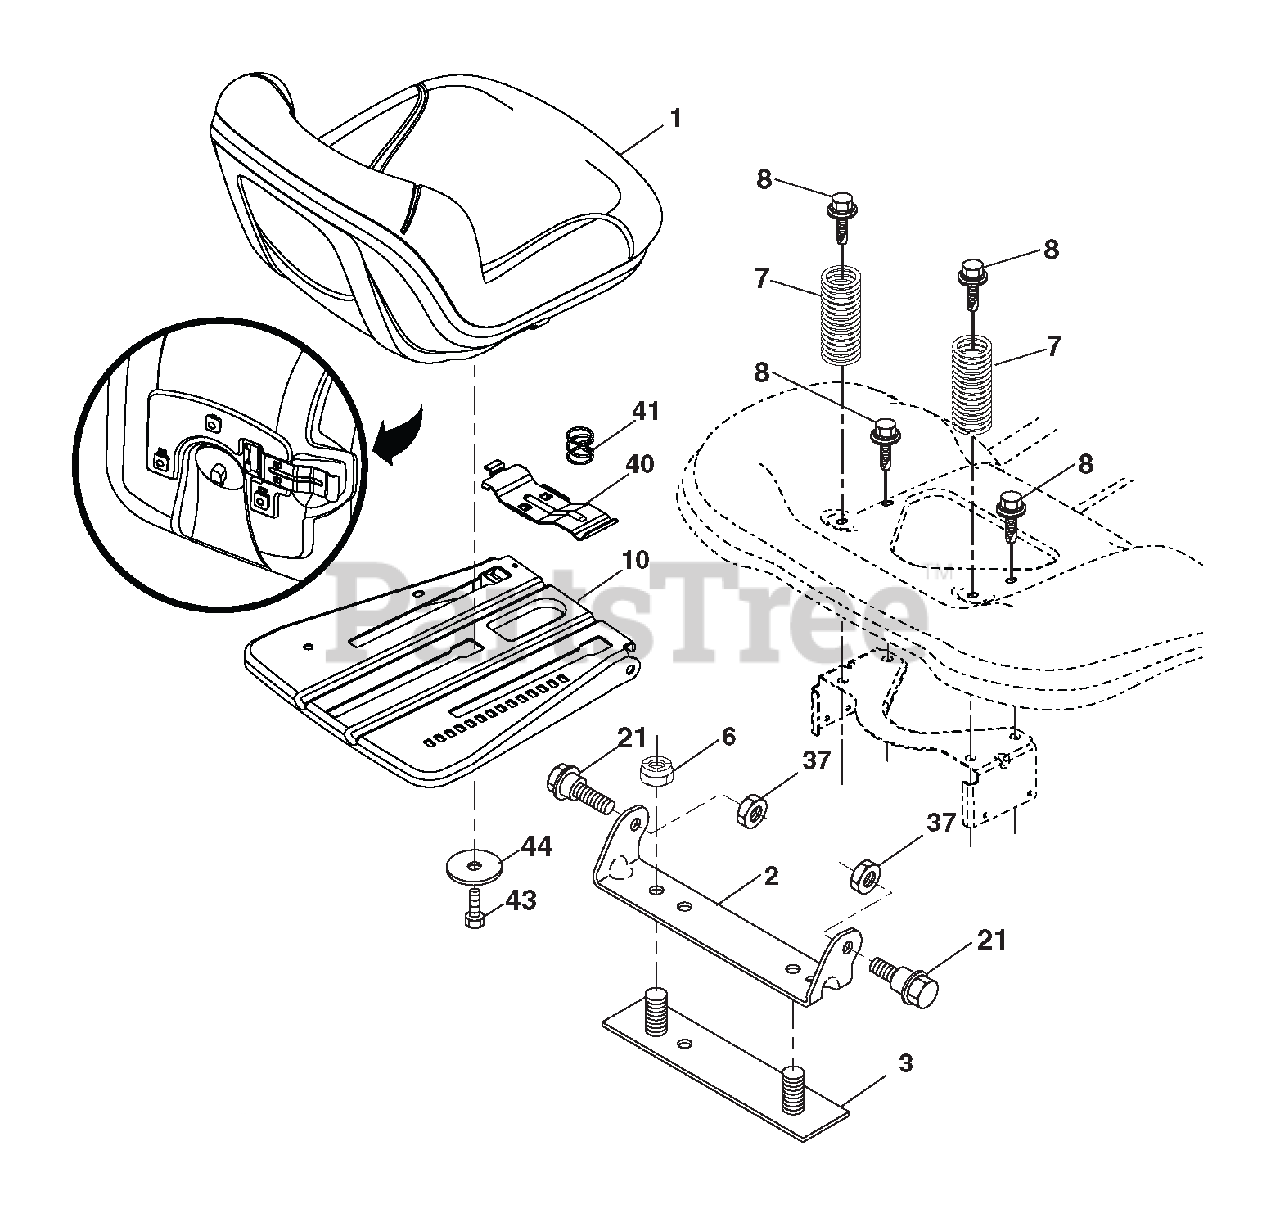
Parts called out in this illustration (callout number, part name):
1	SEAT.TA110.BLACK.ARIENS
2	BRACKET.PIVOT.FENDER.2002
3	STRAP ASM.FENDER.94
6	Locknut, Washer Insert 3/8-16
7	SPRING.SEAT.CPRSN.2.250.BLK.ZI
8	BOLT.5/16-18UNCX3/4 W/SEMS.BLK
10	PAN ASM.SEAT.3PT.
21	BOLT.SHLD.5/16-18 UNC-2A.BLK D
37	Locknut, Washer Insert 5/16-18
40	HANDLE.SLIDE.SEAT.TEX.MILSCO
41	SPRING.LATCH.SEAT.TEX
43	BOLT.FIN.HEX.3/8-16UNC X 3/4
44	WASHER.13/32 X 2 3/8 X 12GA.
